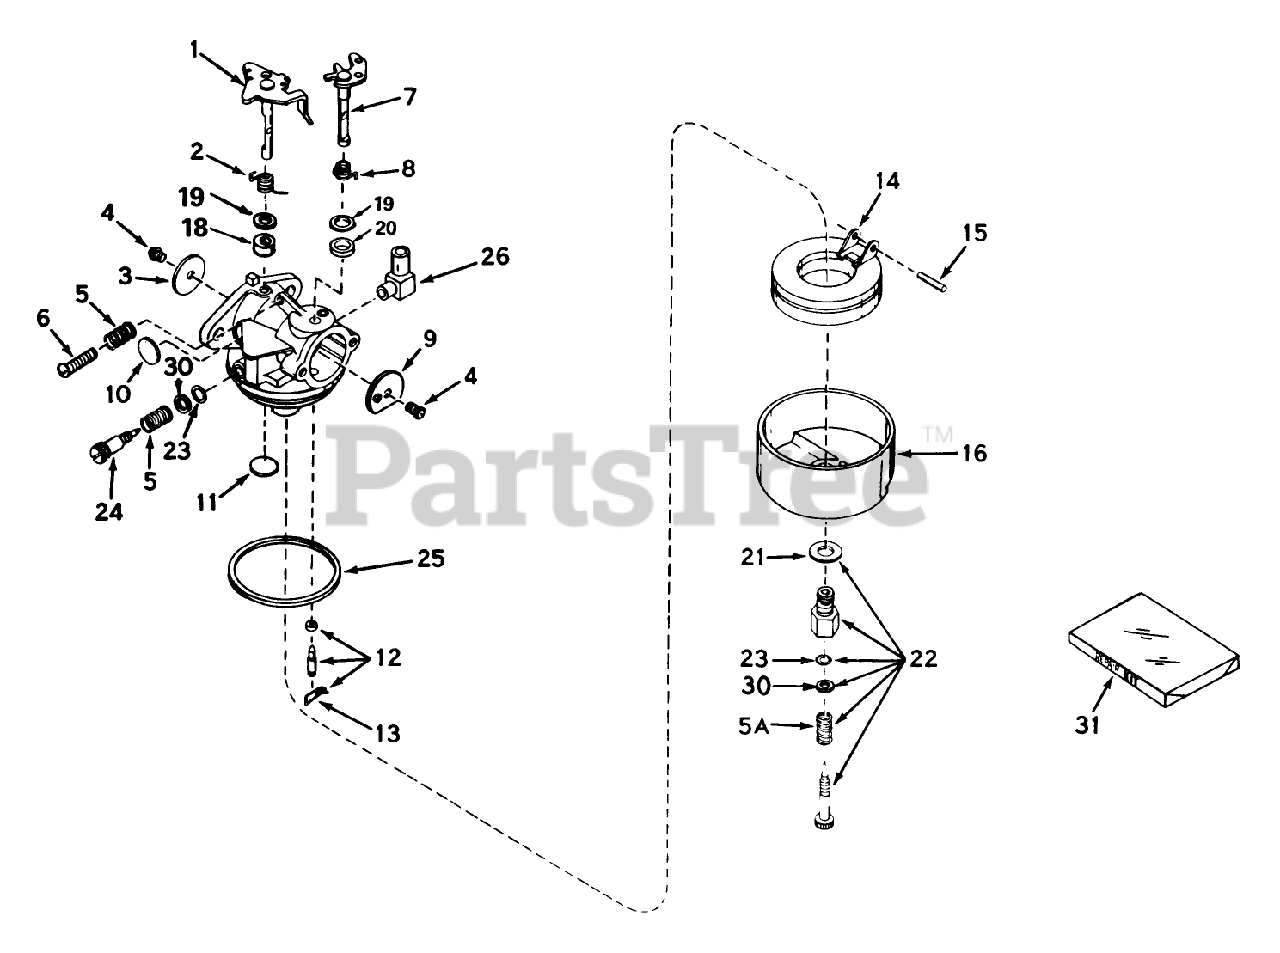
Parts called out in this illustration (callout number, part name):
1	Shaft/Lever-Throttle
2	Spring-Return, Throttle
3	Shutter-Throttle
4	Screw-Shutter
5	Spring-Tension
5A	Spring
6	Screw-Throttle Crack Screw / Idle Speed
7	Shaft Lever Assy., Choke
8	Spring-Choke
9	Shutter-Choke
10	Plug-Welch, Idle Mixture Well
11	Plug-Welch, Atmospheric Vent
12	Inlet Needle, Seat Clip Assy. (Incl. No. 13)
13	Clip-Spring
14	Float
15	Shaft-Float
16	Bowl-Float (no drain)
18	Seal-Dust
19	Washer-Seal, Dust
20	Seal-Dust
21	Washer-Bowl Nut
22	Adjustment Screw Assy., Main (Incl. Nos. 5A, 21 23)
23	ORing
24	Screw, Idle Adj.
25	O Ring-Bowl, Float
26	Fitting-Fuel Inlet
30	Washer
31	Repair Kit
